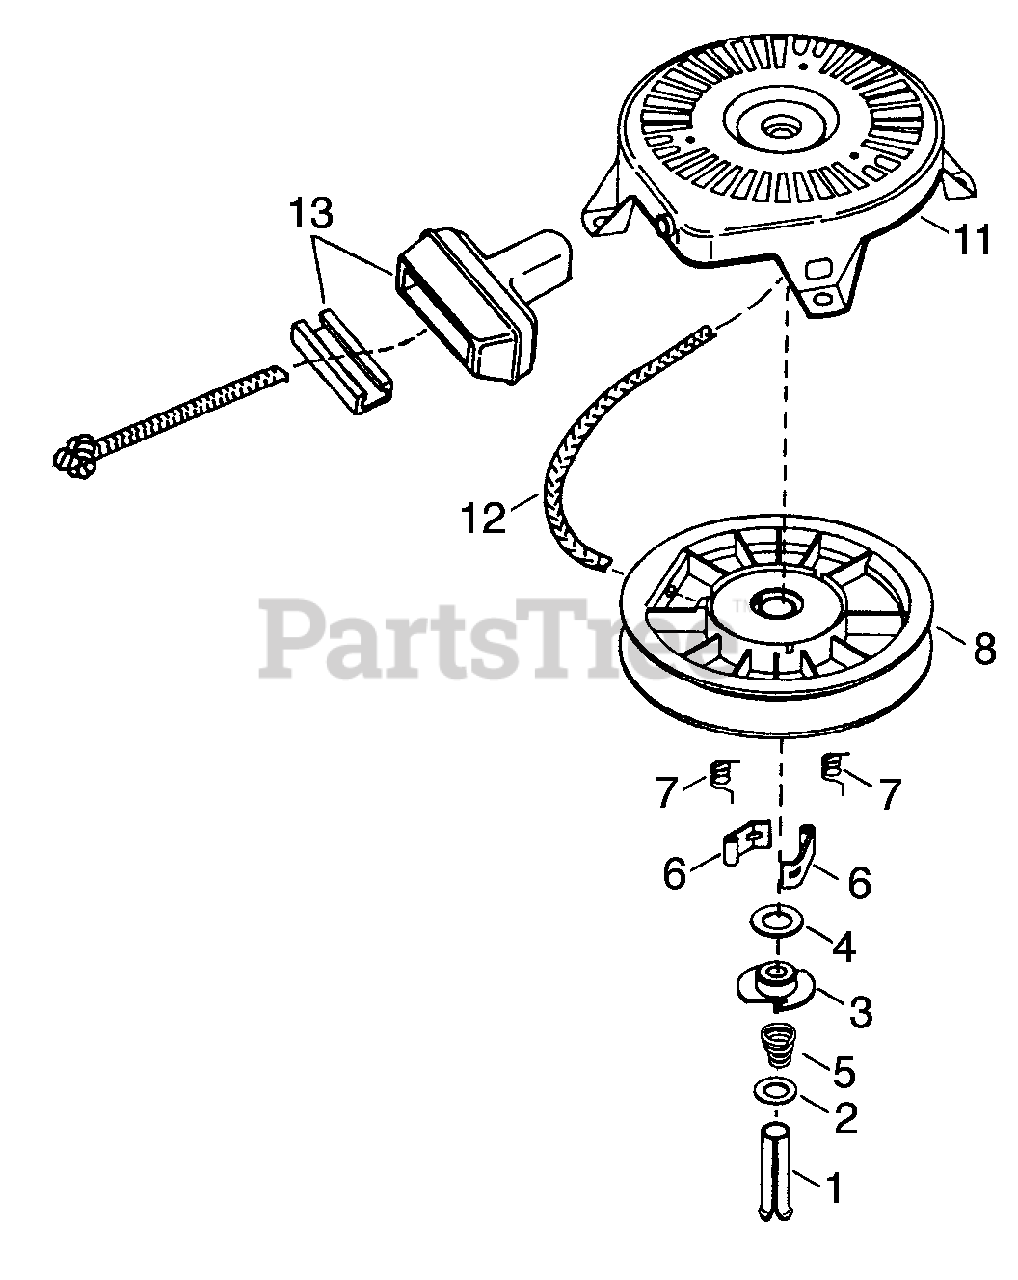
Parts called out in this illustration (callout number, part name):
5	Brake Spring
6	Starter Dog
7	Dog Spring
8	Pulley & Rewind Spring Assy
11	Starter Housing Assy
12	Starter Rope
13	Starter Handle
